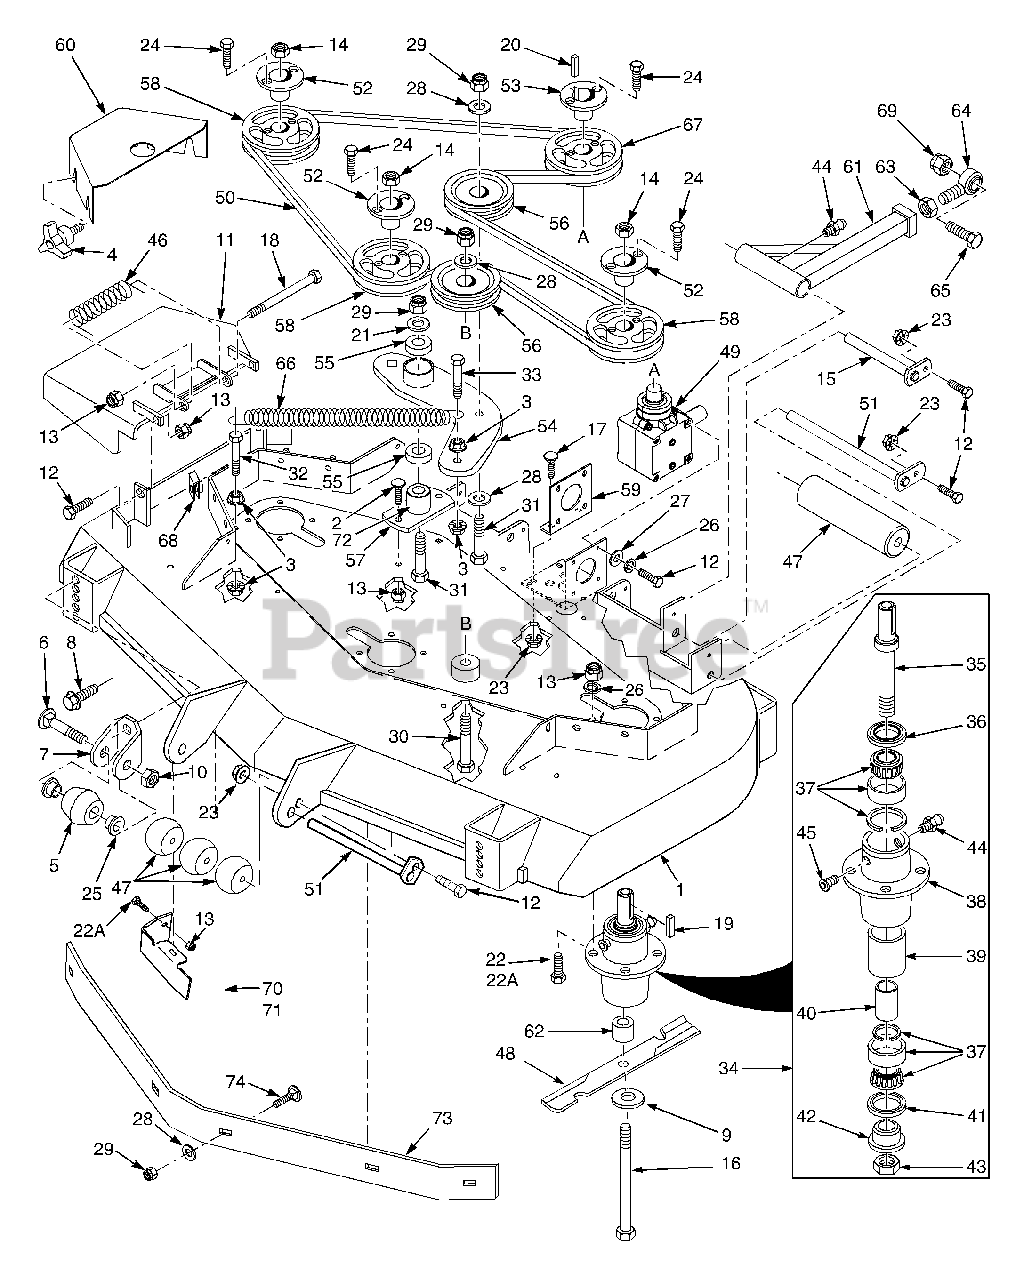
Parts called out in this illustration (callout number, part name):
1	Cutter Deck Advantage
2	Bolt, Carriage 5/16-18 x 1"
3	Nut, Hex Serrated Flange 3/8-16
4	Wing nut, 3/8-16
5	Anti-Scalp Wheel
6	Bolt, Carriage 3/8-16 x 4"
7	Anti-Scalp Wheel Bracket
8	Bolt, Hex Serrated Flange 3/8-16 x 1"
9	Flatwasher, 5/8" Hardened
10	Locknut, 3/8-16 Center Lock
11	Discharge Chute Advantage - Small
12	Bolt, Hex Head 5/16-18 x 1-3/4" - Front
13	Nut, Hex Elastic Stop 5/16-18 Grade 8
14	Nut, 5/8-11 UNC
15	Push Arm Shaft
16	Bolt, Hex Head 5/8-11 x 9-1/2"
17	Bolt, Carriage 5/16-18 x 3/4"
18	Bolt, Hex Head 5/16-18 x 4-1/2"
19	Key, 1/4 x 1/4 x 2"
20	Key, 1/4 x 1/4 x 1-1/4"
21	Flatwasher,3/8-.39 x .938 x .105 HD
22	Bolt, Hex Head 5/16-18 x 1-3/4"
23	Nut, Hex Serrated Flange 5/16-18
24	Bolt, Hex Head 1/4-20 x 1" Grade 8
25	Bushing, .376 I.D. Oilite
26	Lockwasher, 5/16"
27	Flatwasher, 5/16" (.375 x .875 x .083)
28	Flatwasher, 3/8" (.391 x .938 x .105)
29	Nut, Hex Elastic Stop 3/8-16
30	Bolt, Hex Head 3/8-16 x 3-1/4"
31	Bolt, Hex Head 3/8-16 x 2-1/2"
32	Bolt, Hex Head 3/8-16 x 1-1/2"
33	Bolt, Hex Head 3/8-16 x 1-1/2" Grade 8
34	Spindle Assembly
35	Spindle Shaft
36	Seal, Top
37	Bearing Assembly
38	Spindle Housing
39	Spacer, Outside
40	Spacer, Inside
41	Seal, Bottom
42	Spindle Bushing, Bottom
43	Nut, Special 1 - 1/16-18
44	Grease Fitting
45	Relief Fitting, Tapered Spindle
46	Spring, Discharge Chute
47	Wheel, Anti-Scalp
48	Cutter Blade, 18"
49	Gearbox Assembly, Deck Drive
50	Belt, Cutter Deck Drive
51	Roller Shaft
52	Tapered Hub, 1-1/8" Bore
53	Tapered Hub, 1" Bore
54	Idler Arm, Cutter Deck
55	Bearings, Ball
56	Pulley, Idler
57	Base, Idler Pivot
58	Pulley, 5.75 O.D. (52')
59	Mounting Plate, Gearbox
60	Belt, Cover
61	Pusharm
62	Spacer, Spindle Bottom
63	Nut, Hex Head 5/8-18 UNF
64	Rod End, 5/8" Male RH Thread
65	Bolt, Hex Head 5/8-11 x 4-1/2"
66	Spring, Cutter Deck
67	Pulley, 6.95 O.D.
68	U-Nut, 3/8-16
69	Nut, Hex Elastic Stop 5/8-11
70	Discharge Baffle 52"
72	Pivot, Idler - Short
73	Baffle, Custom Cut 52A
74	Bolt, Carriage 3/8-16 x 1"
